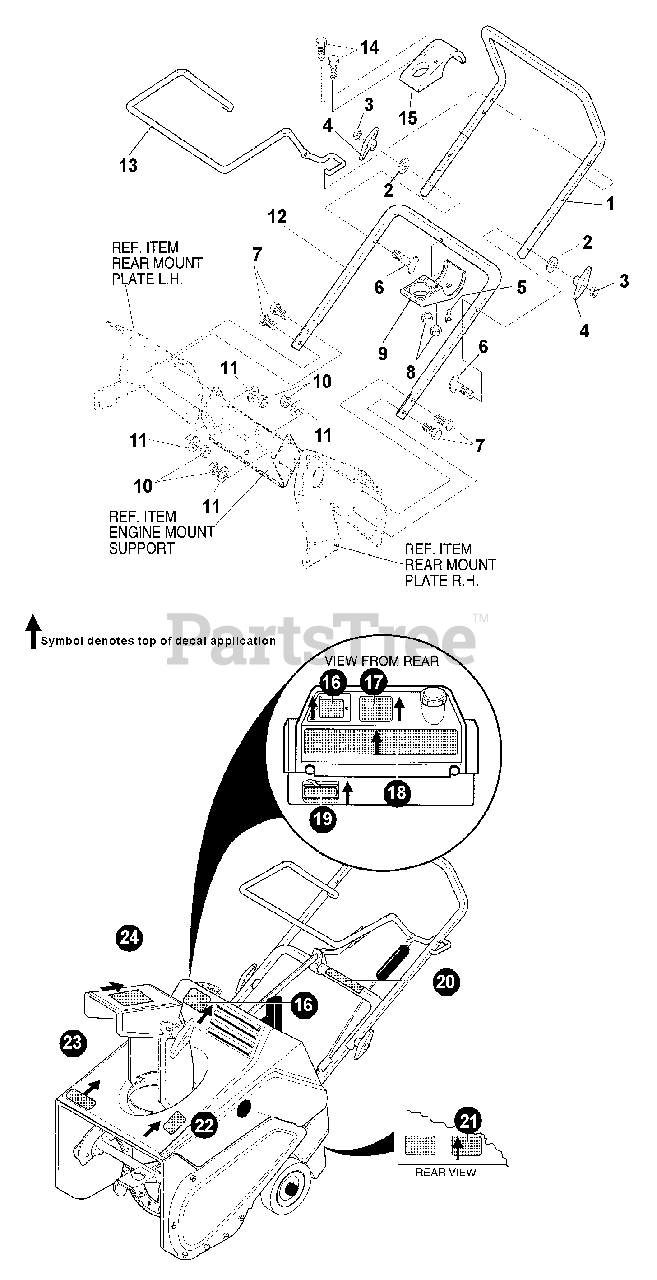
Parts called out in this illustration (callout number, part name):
1	HANDLE, UPPER
2	WASHER
4	KNOB, T 2 BLADE W/5/16-18 NUT
5	SCREW 1/4"-20×0.63
6	BOLT, 5/16-18×2.00
7	SCREW 5/16"-18×0.75
8	NUT, 10-24
9	BRKT HALF, CHUTE CRANK
10	NUT, 5/16"-18
11	WASHER
12	HANDLE, LOWER
13	BAR, DRIVE CONTROL LOOP
14	SCREW #10-24×1.00
15	BRKT HALF, CHUTE CRANK
16	LABEL - ECHO -- ST-5000E
17	LABEL - STARTING
18	LABEL - CONTROL PANEL
19	LABEL - CHOKE
20	LABEL - AUGER CONTROL BAR
21	LABEL - EPA
22	LABEL - DANGER
23	LABEL - ECHO
24	LABEL - DANGER
